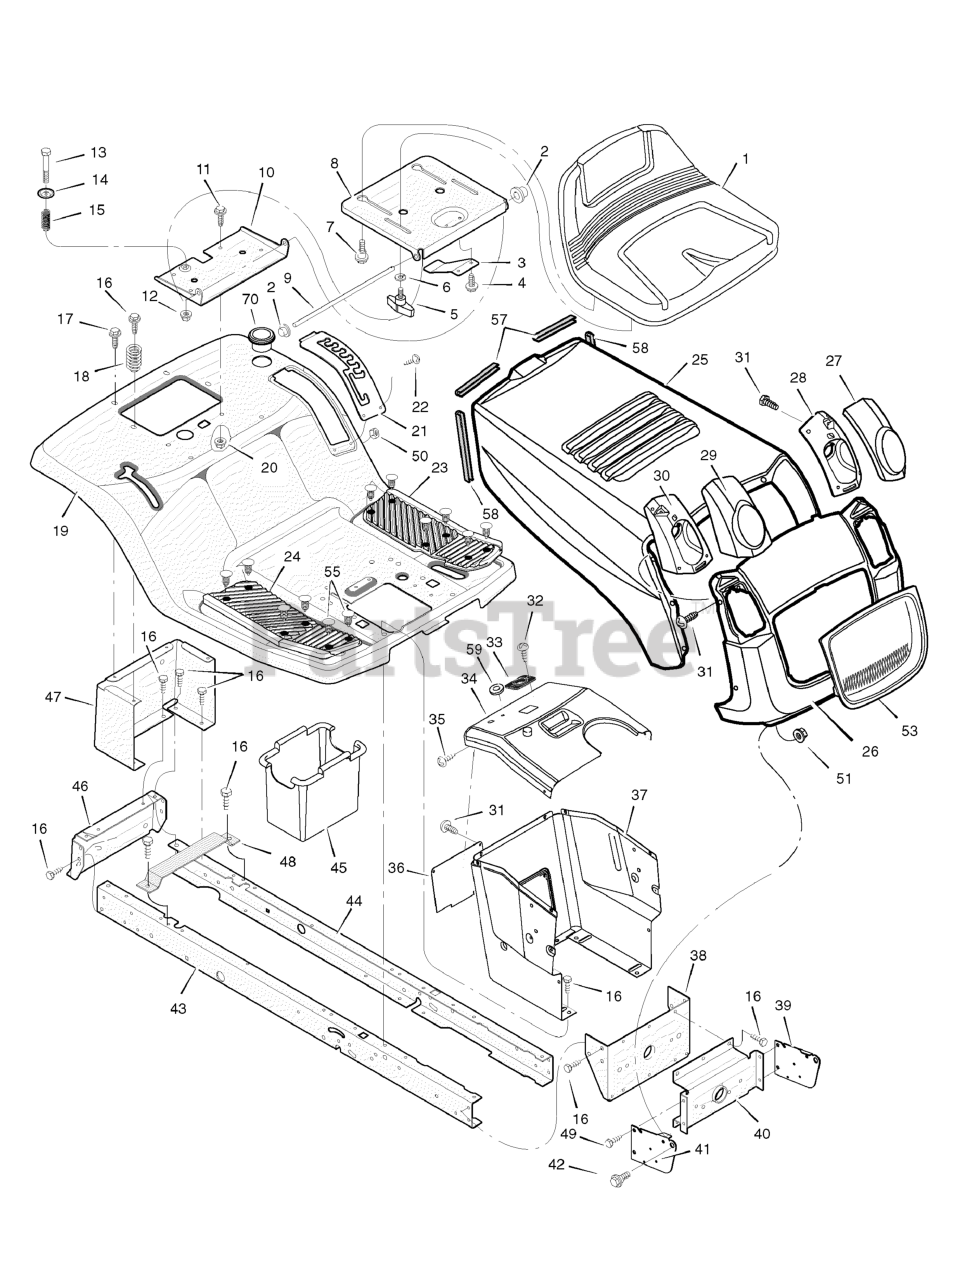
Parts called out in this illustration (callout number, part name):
1	Seat
2	Cap, Push 0n
5	Bolt, Wing
6	Washer
7	Bolt, Shoulder
8	Support, Seat
9	Rod, Pivot
10	Bracket, Pivot
11	Bolt
13	Bolt, Shoulder
20	Nut
21	Plate, Index
23	Mat, Left
24	Mat, Right
27	Lens, Left
28	Housing, Left Headlamp
29	Lens, Right
30	Housing, Right Headlamp
33	Bearing, Steering
34	Dash
36	Panel, Access
37	Support, Dash
38	Bracket, Rear Hanger
39	Support, Left Grille
40	Axle, Hanger
41	Support, Right Grille
42	Bolt, Shoulder
43	Frame, Right
44	Frame, Left
45	Container, Battery
46	Plate, Hitch
47	Panel, Rear
48	Support, Battery
53	Insert, Grille
55	Fastener, Panel
57	Trim, Hood (3.75")
58	Trim, Hood (6.5")
59	Grommet, Parking Brake
70	Holder, Cup
